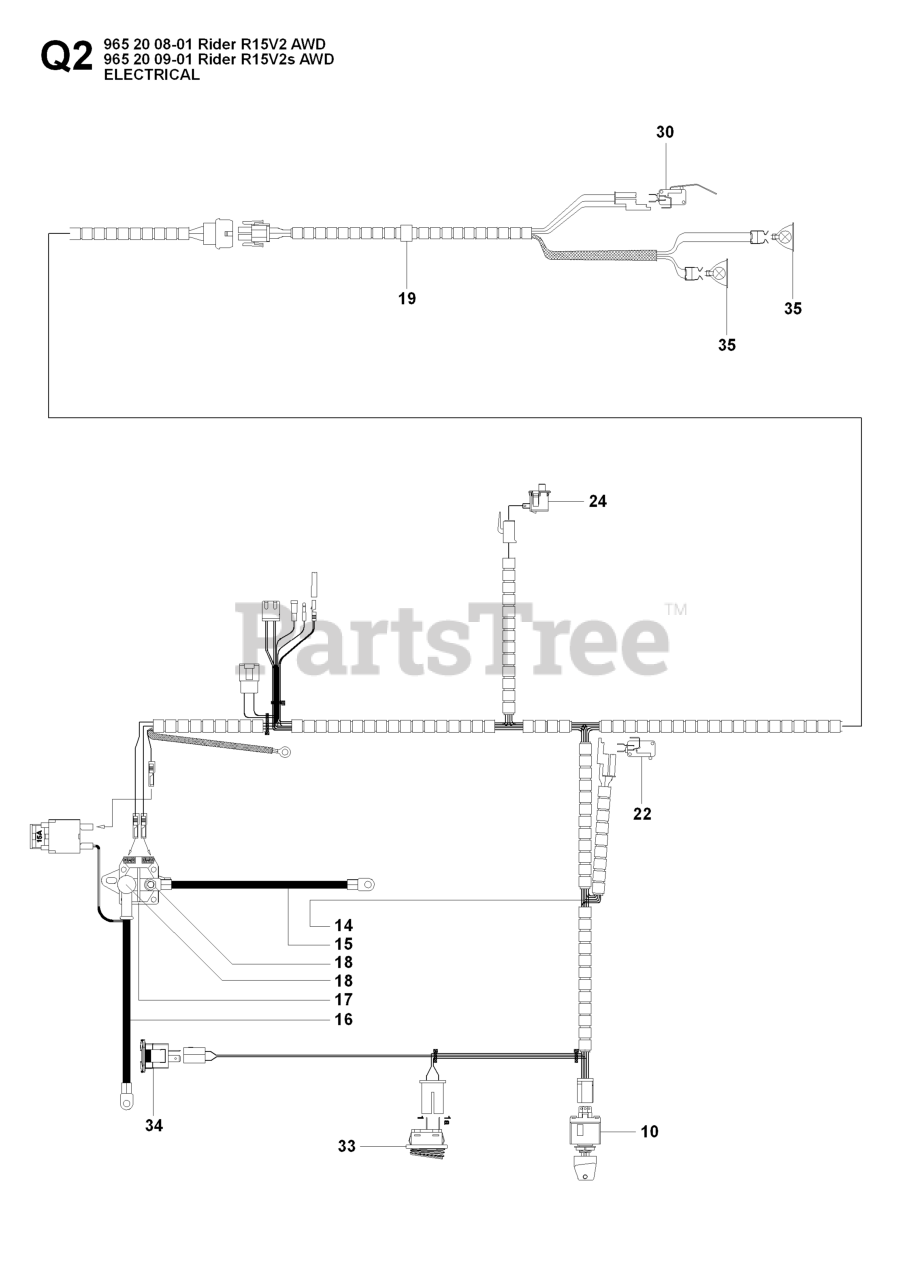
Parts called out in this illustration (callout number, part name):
10	IGNITION SWITCH
19	WIRING
22	%BRAKER
30	RP MICRO SWITCH
